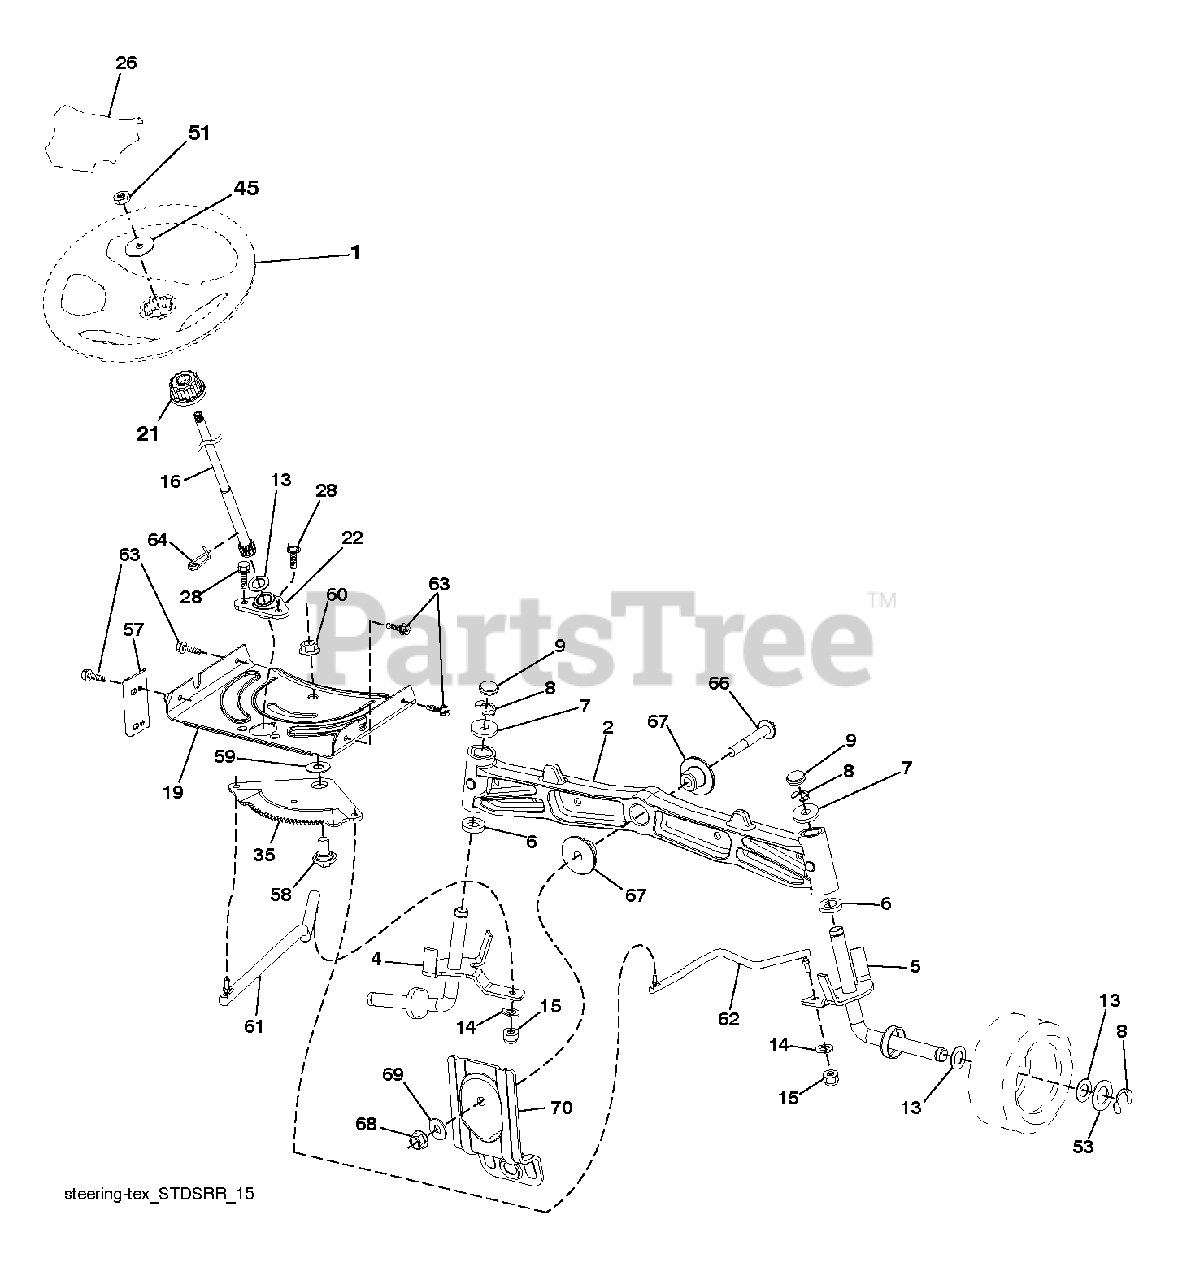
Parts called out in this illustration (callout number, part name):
1	RP WHEEL.STEER.HUSQ.PREM.OVMLD
2	AXLE.CAST.IRON
4	SPINDLE.WELDED.LH.15"TEX
5	SPINDLE.WELDED.RH.15"T
6	THRUST WASHER
9	CAP.SPINDLE.BLACK
14	WASHER, LOCK 3/8
15	NUT CROWNLOCK 3/8-24
16	SHAFT.STEER.STEALTH.DD
19	PLATE.STEER.DDL.NLT/NG
21	ADAPTER, WHEEL STNG..
22	STEERING.SUPT.LOWER.
26	RP INSERT.CAP.WHL.STRG.HUSQ.
28	SCREW, 3/8-16X3/4
35	GEAR.SECTOR.PLATE.DDL.
45	WASHER 9/16"ID, 2 3/8"OD
51	NUT.HEX.1/2-20
53	WASHER.HARDENED
57	BRACKET.UPSTOP.TEX
58	BOLT.SHOULDER.SECTOR.P
59	WASHER.THURST.SECTOR.S
60	NUT FLANGE LOCK 5/8-11
61	DRAGLINK.LH.BALLSTUD.D
62	DRAGLINK.RH.BALLSTUD.D
63	SCREW
64	RETAINER.CLIP.SPRING.S
66	BOLT HEX FGHD 7/16-14 X 3 SERR
67	BUSHING.PM.FRONT AXLE
68	NUT.LOCK.FLANGE.7/16
69	WASHER.1.5X.505X.118
70	BRKT.DECK.SUSPENSION.F
